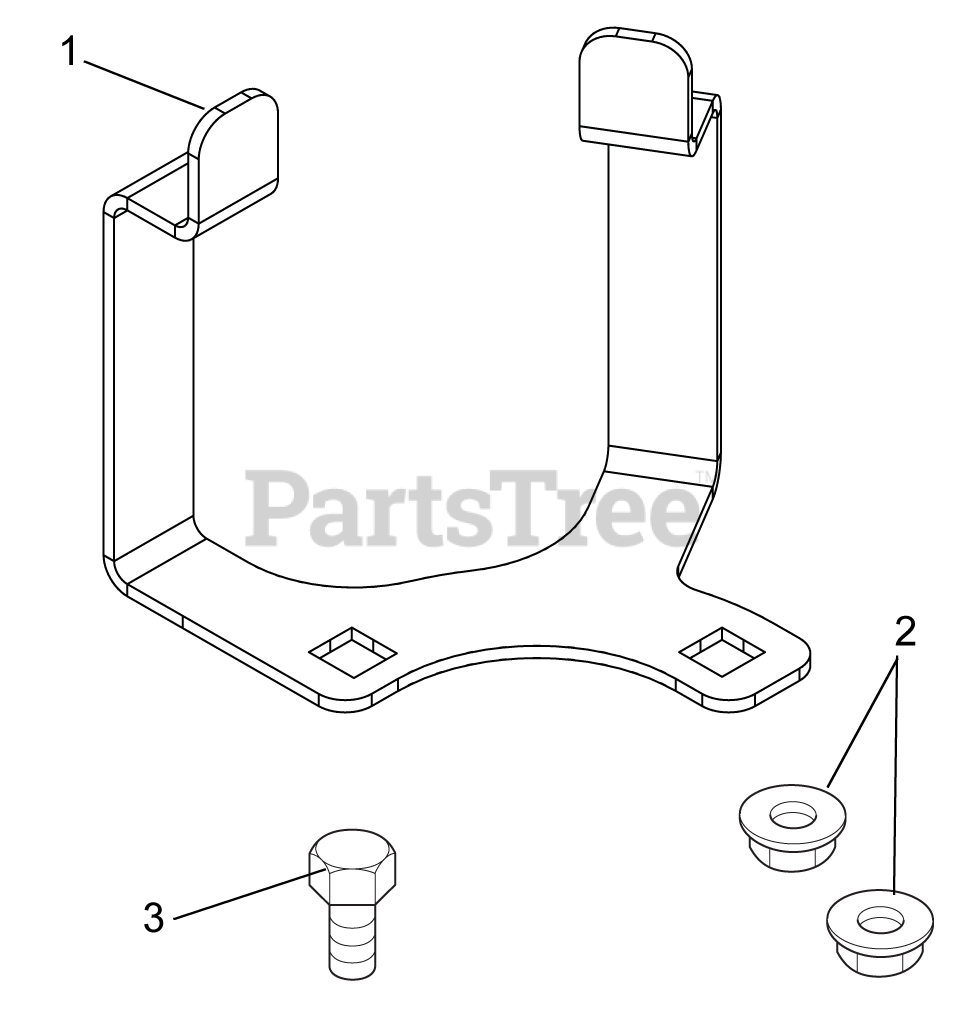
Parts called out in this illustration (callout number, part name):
1	FINGER, JACKSHAFT BELT
2	@NUT-LK-NYL-FLG .38-16 YWZC
3	BLT-HEX .38-16X1.0 GR8 YZ EP30
